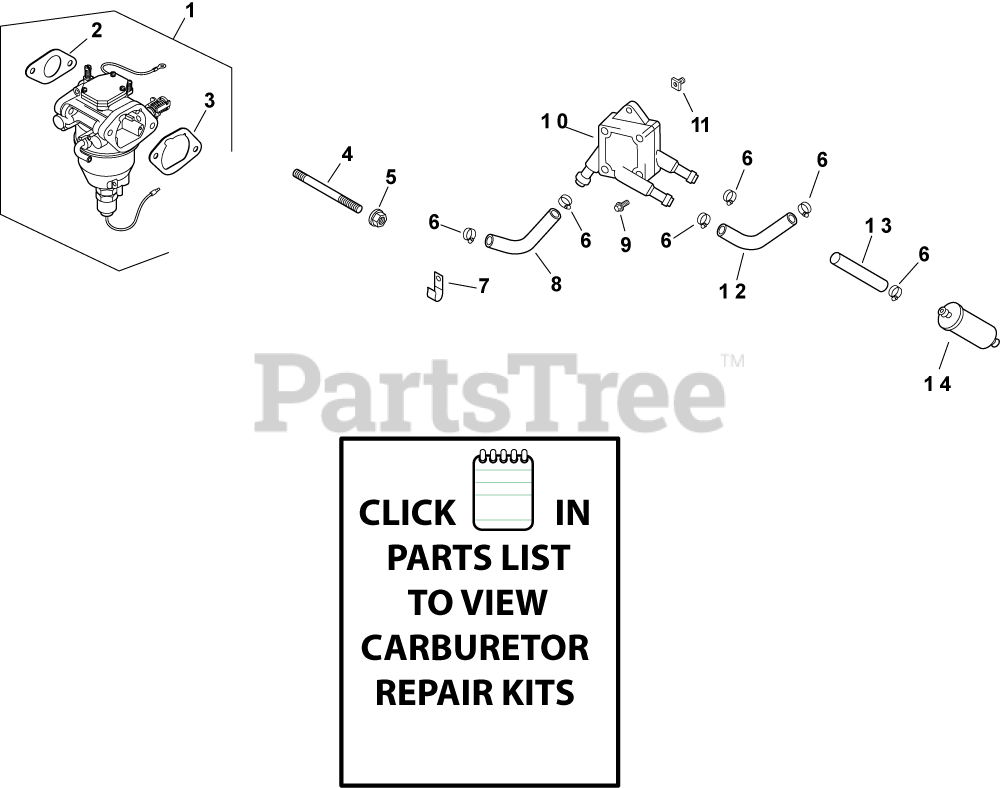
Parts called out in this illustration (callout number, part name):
2	GASKET, CARBURETOR
3	GASKET, AIR CLEANER BASE
4	STUD,M6X1.0X128
5	NUT, FLG M6X1.0
6	CLAMP, HOSE (KM)-USE 25 237 31-S
7	CLIP, CABLE
8	LINE, FUEL 11"
9	SCREW, TAP M6X1.7X18
10	PUMP, FUEL
11	NUT, PLASTIC (KM)-USE 25 100 37-S
12	LINE, FLEXIBLE FUEL 12.3"-USE 25 111 81-
13	LINE, FLEXIBLE FUEL
